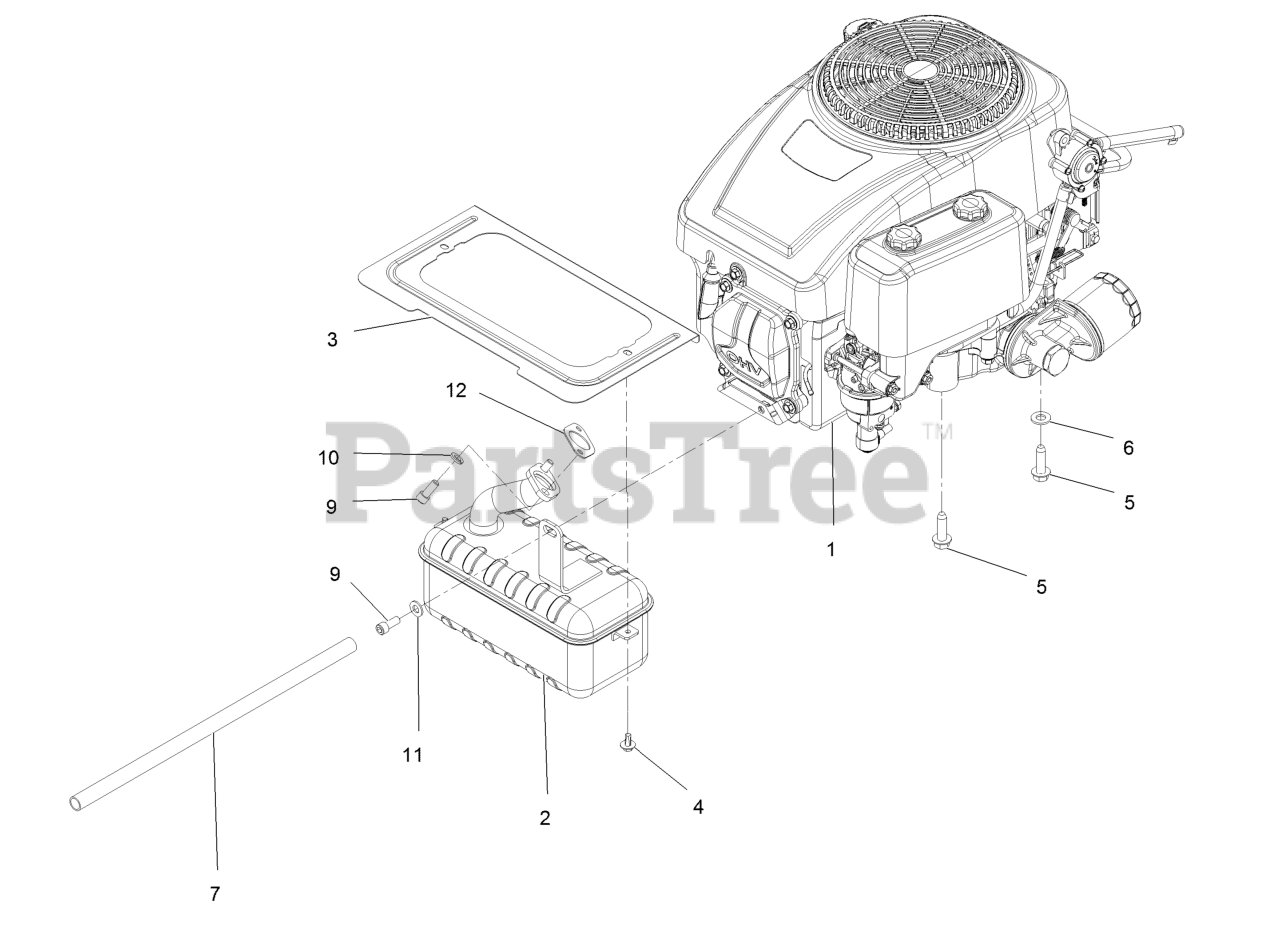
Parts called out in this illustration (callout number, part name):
2	MUFFLER
3	SHIELD-HEAT
4	SCREW-HHFTF
5	SCREW-THD
6	WASHER-FLAT
7	TUBE-DRAIN, OIL
9	SCREW-HSH
10	WASHER-LOCK
11	WASHER-PLAIN
12	GASKET-EXHAUST
